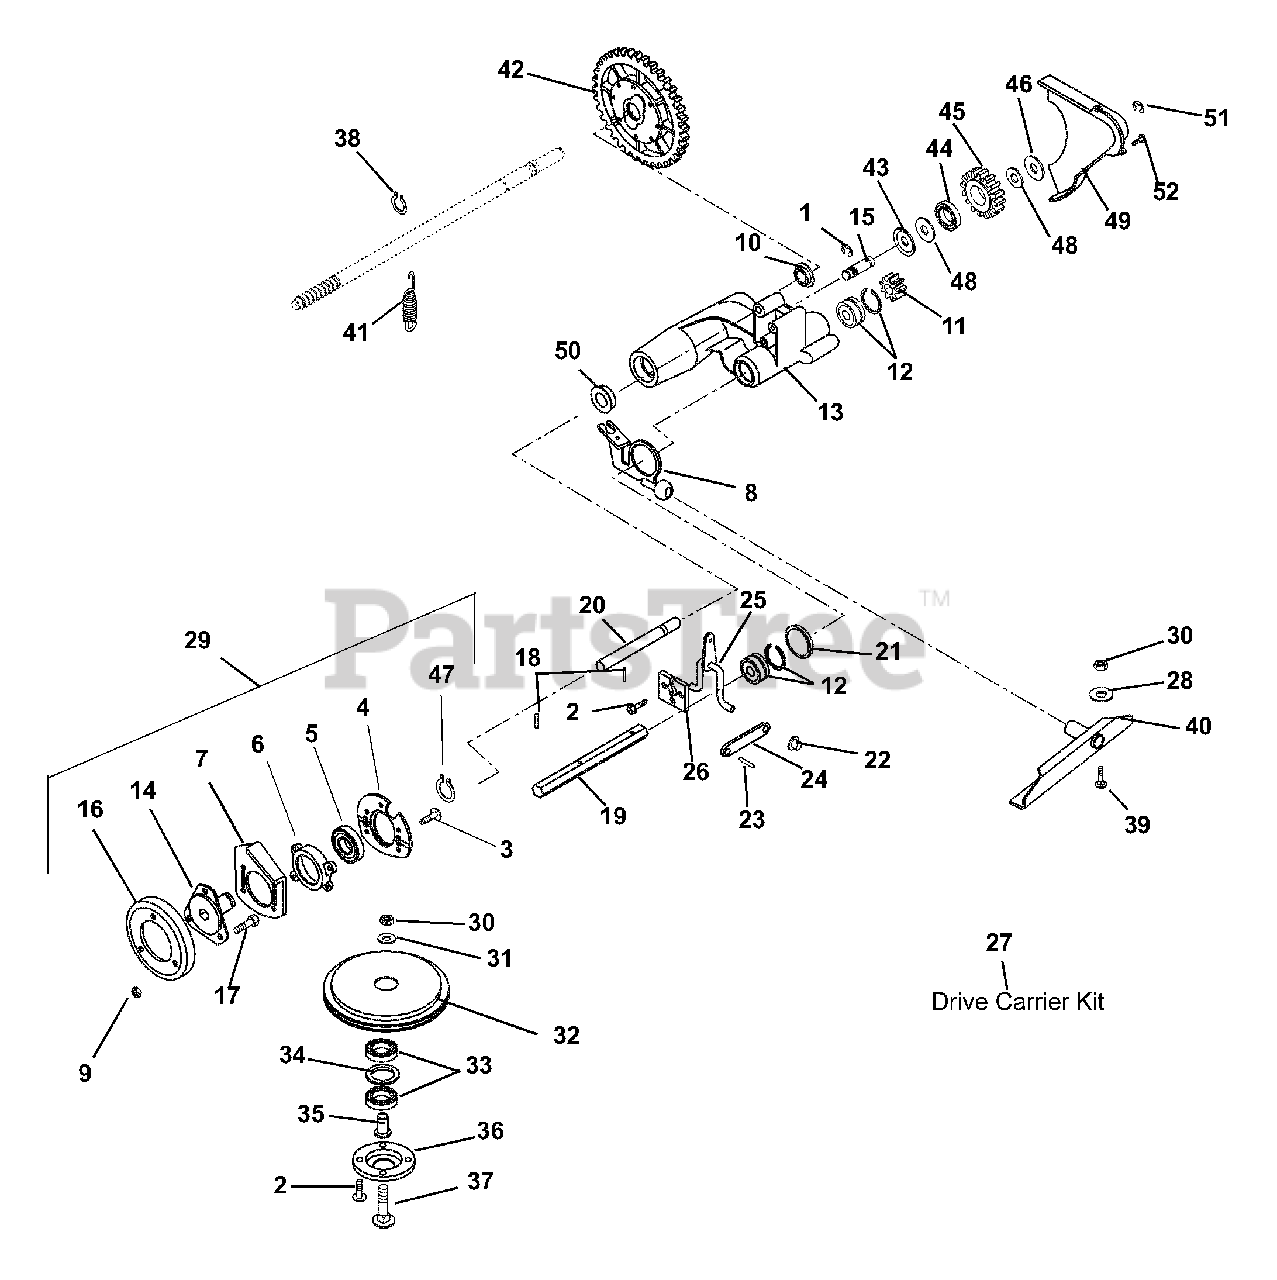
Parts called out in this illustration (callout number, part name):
1	RG-RTNG-EXT .438X.035
2	@SCR-TAP 12-24X.50 HWH TR YWZC
3	SCR-TAP 5HX-0.8X16MM H-FL-YWZC
4	BEARING RETAINER
5	BRG-BALL 1.0X2.0X.56 (1641)
6	BEARING RETAINER
7	PLATE, BEARING
8	ACTUATOR, WBLM DRIVE
9	@NUT-LK-CTR .25-20 YWZC
10	BRG-BALL .625X1.378X.44
12	BRG-BALL .562X1.375X.437
13	DRIVE CARRIER
14	FRICTION WHEEL HUB
15	IDLER SHAFT
16	DISC, FRICTION - 730 MAT'L
17	@BLT-HEX .25-20X.50 GR5 YWZC
18	PIN-ROLL .188X.88
19	SHAFT, HEX
20	ROD - GUIDE
21	WSHR-FL-STL 1.390X2.00X.020 PL
22	PUSH NUT, .25
23	PIN-ROLL .125X.50
24	SHIFT LINK
25	SHIFT ARM WELDMENT
26	RETAINER PLATE
27	KIT, LM DRIVE CARRIER
28	@WSHR-FL-STL.344X.688X.065YWZC
29	FRICTION WHEEL ASSEMBLY
30	@NUT-LK-CTR .31-18 YWZC
31	WSHR-FL-STL .328X.87X.179 YWZC
32	FRICTION SHEAVE
33	BRG-BALL .625X1.375X.43
34	WSHR-FL-STL 1.062X1.344X.032PL
35	SPINDLE - BEARING
36	RETAINER - BEARING
37	@BLT-RDHDSQNK .31-18X1.75 G5YZ
38	RG-RTNG-EXT .579X.035
39	@BLT-RHDSSQNK .31-18X.62 G5YZ
40	PIVOT, CHANNEL WELDMENT
41	SG-TENS .051X.60X2.25 WLD 7.0
42	DIFFERENTIAL ASSEMBLY
43	RETAINER
44	BRG-BALL .500X1.38X.437
45	IDLER GEAR
46	WSHR-FL-STL.531X1.00X.063 YWZC
47	RG-RTNG-EXT 1.00X.042
48	WSHR-FL-STL .52X.827X.062 YWZC
49	COVER, GEAR
50	BRG-BALL .625X1.383X.50
51	RG-RTNG-EXT .438X.035
52	@SCR-TAP 12-24X.50 HWH TR YWZC
